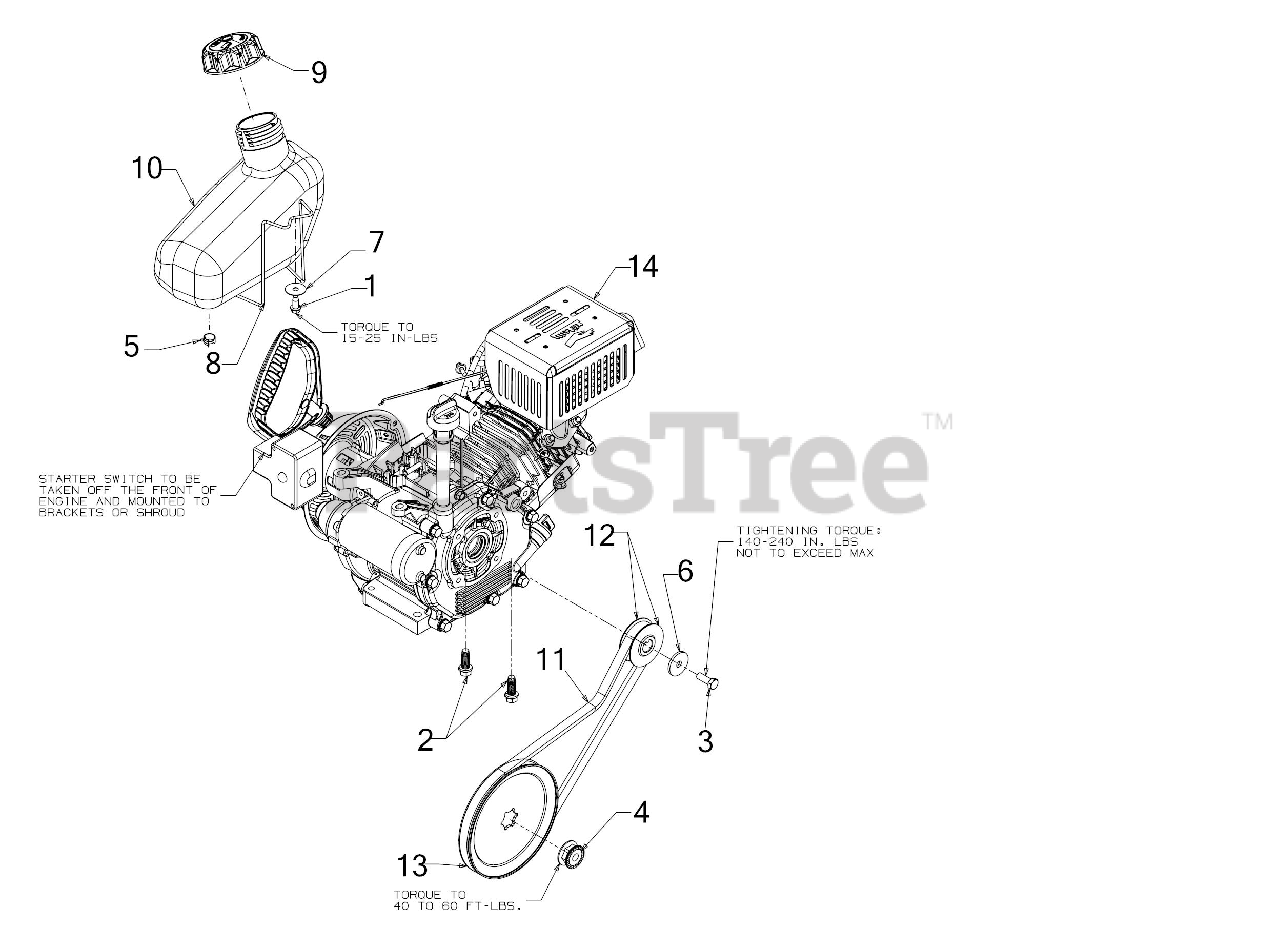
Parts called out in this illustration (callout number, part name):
1	SCREW 1/4-10:.625
2	SCREW 3/8-16 x 1
3	SCREW 5/16-24 x .875 GR5
4	FLANGE NUT W/HUB
5	HOSE CLAMP 1/20
6	WASHER-5/16 x 1.25X 1.27
7	FLAT WASHER
8	SUPPORT WIRE
9	FUEL CAP THREAD VENT
10	FUEL TANK (2 QT)
11	V-BELT .500 x 35.
12	HALF PULLEY
13	AUGER PULLEY
14	COMPLETE ENGINE 208cc
